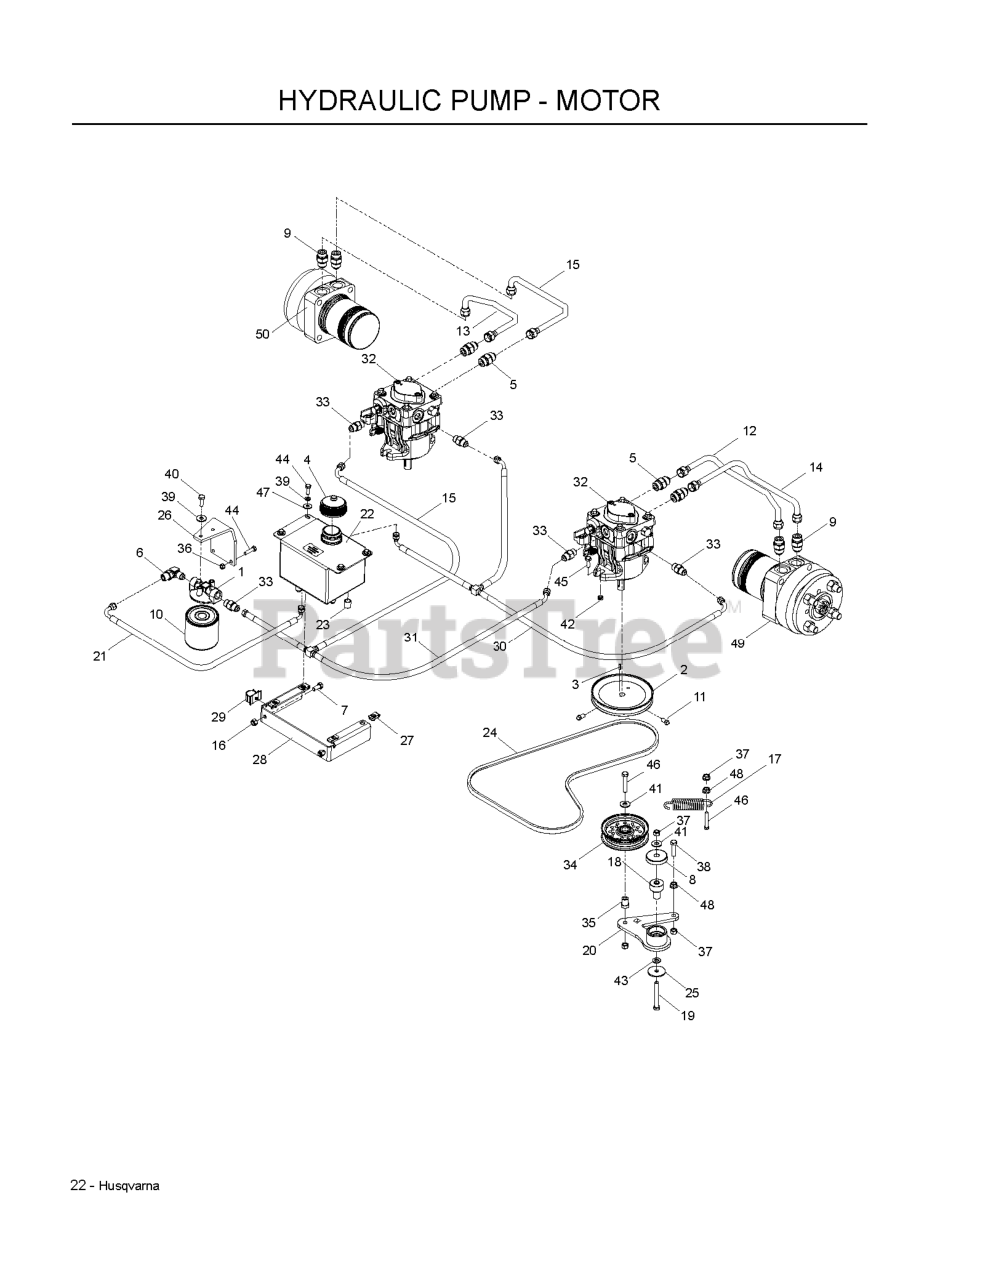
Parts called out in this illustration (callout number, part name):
1	FILTER HEAD
3	KEY 5 MM SQ X 25 MM
4	HYDRAULIC CAP
5	FITTING, STRAIGHT F6400-8-8-0
6	ELBOW, F6801-6-6-0 90 DEGREE
7	HCS 5/16C X 3/4
8	SHIELD, DUST
10	HYDRAULIC OIL FILTER
11	SCREW 5/16C X 5/8 SQ HEAD
12	HOSE, RPA - MA LINE
13	HOSE, RPB - MB, LINE
14	HOSE, LPA - MB LINE
15	HOSE, LPB - MA LINE
16	NUT 5/16 NYLOC
18	PIVOT, BEARING
19	HCS 3/8C X 3
20	ARM, IDLER - W/BEARINGS
21	HOSE, TANK - FILTER LINE
23	NUT 9/16-18 JIC CAP
24	BELT, PUMP
25	WASHER, 3/8 SPEC
26	OIL FILTER BRKT
27	1/4C - U TYPE RETAINER
28	TANK MOUNT
29	PUSH-MOUNT WIRE CLIP
30	HOSE, T-ASM RETURN
31	HOSE, T-ASM SUPPLY
32	HG_PUMP, 10CC W/O FAN
33	HYDRAULIC FITTING
34	IDLER PULLEY
35	BUSHING, IDLER FLANGE
36	NUT.1/4-20.HEX.NYLOC.ZD
37	NUT 3/8-16 NYLOC
38	HCS 3/8C X 1 1/2
39	LOCKWASHER 1/4"
40	HCS 1/4C X 5/8
41	WASHER 3/8 FLAT
42	NUT 3/8C CENTERBLOCK
43	WASHER 3/8 SAE FLAT
44	HCS 1/4C X 3/4 HCS
45	4CS 3/8C X 1 SERRATED HEAD
46	HCS 3/8C X 2
47	WASHER 1/4 FLAT
48	NUT 3/8C WHIZ
49	TL15 WHEEL MOTOR
